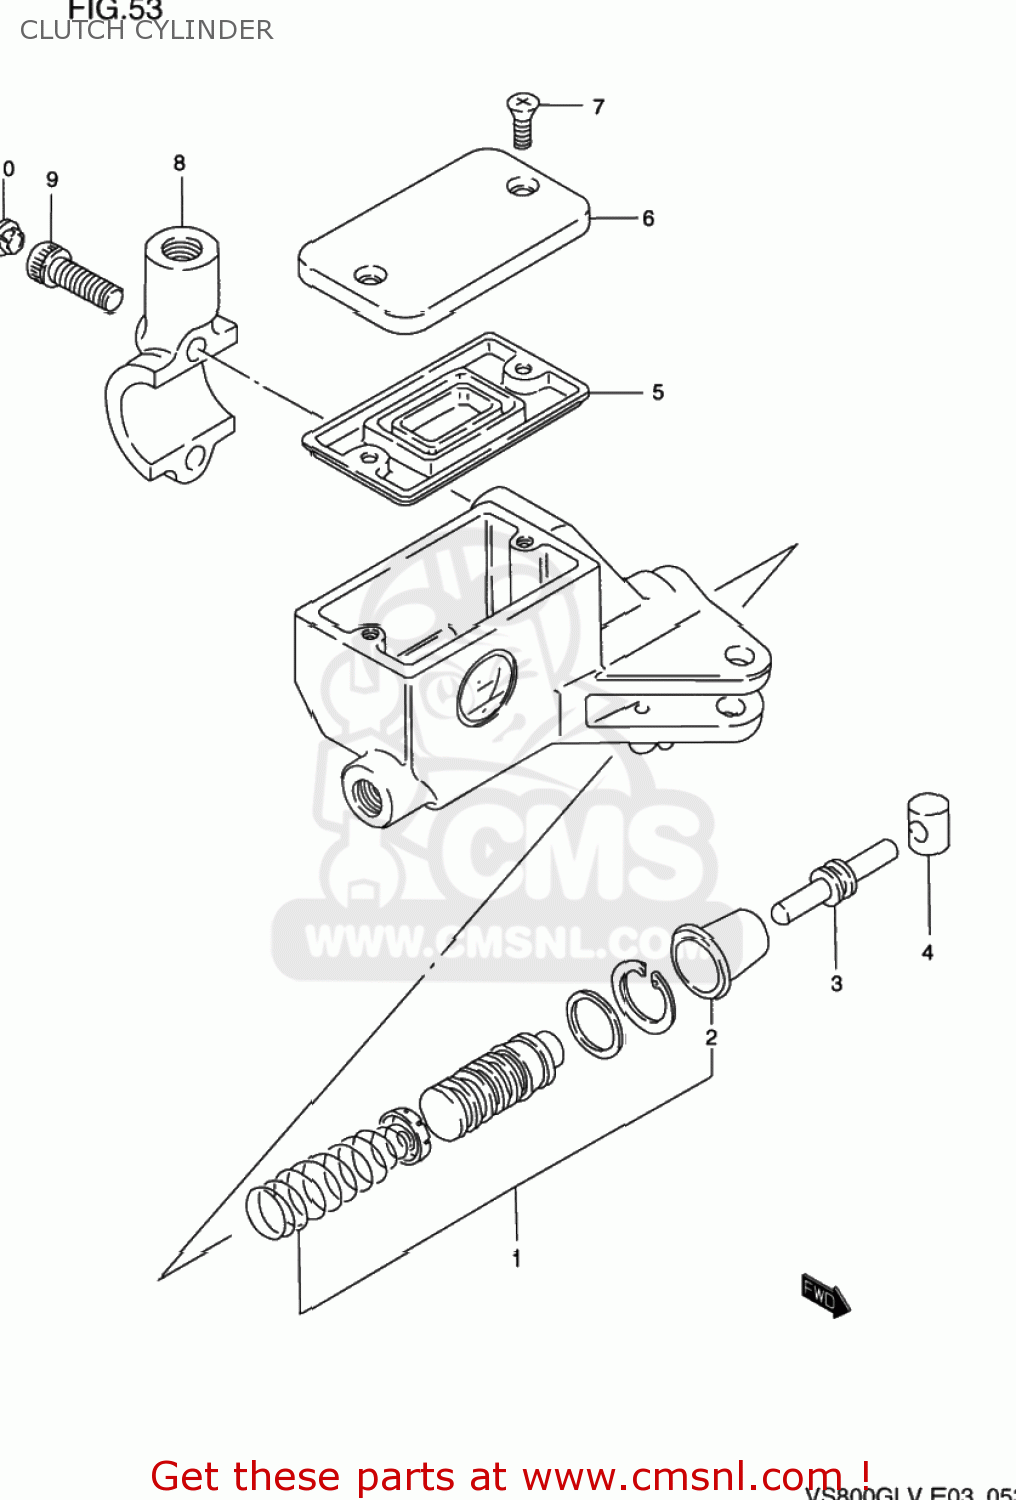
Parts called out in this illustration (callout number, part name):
1	PISTON & CUP SET
2	BOOT
3	PUSH ROD
4	BUSH
5	6
6	CAP
7	SCREW
8	HOLDER
9	BOLT
10	CAP(OD:10)
